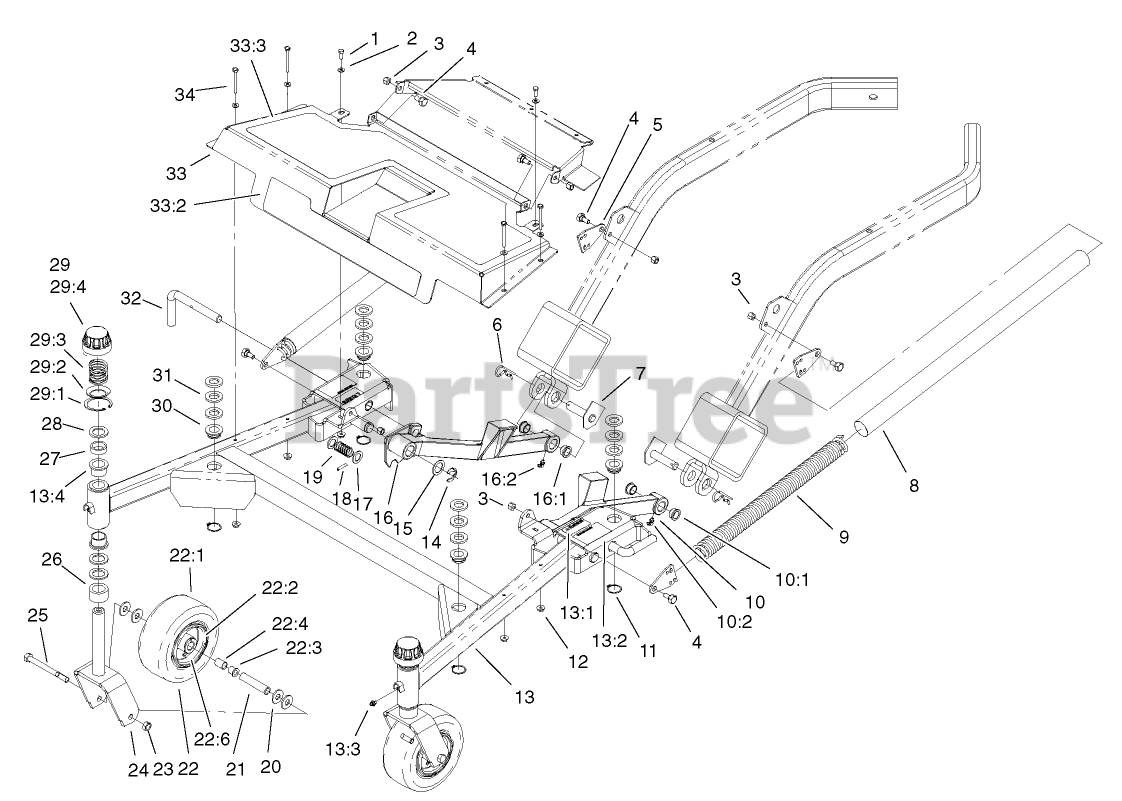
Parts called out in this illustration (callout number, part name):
1	SCREW-HH
2	WASHER-FLAT
3	NUT-LOCK, NI
4	BOLT-SHOULDER
5	PLATE-END, SPRING
6	PIN-HAIR
7	PIVOT PIN ASM
8	COVER-SPRING
9	SPRING-EXTENSION
10	LH PUSHARM ASM
10:1	BEARING-FLANGE
10:2	FITTING-GREASE
11	RING-RETAINING
12	NUT-HF
13	CARRIER FRAME ASM
13:1	DECAL-WARNING
13:2	DECAL - HOC, CE
13:3	FITTING-GREASE
13:4	BUSHING
14	RING-RETAINING
15	Washer
16	RH PUSHARM ASM
16:1	BEARING-FLANGE
16:2	FITTING-GREASE
17	WASHER
18	PIN-ROLL
19	SPRING-COMPRESSION
20	WASHER-FLAT
21	SPANNER-TIRE
22	CASTOR WHEEL ASM
22:2	RIM ASM
22:3	BEARING-OUTSIDE
22:4	BEARING-ROLLER
22:6	FITTING-LUBE, 45 DEG
23	NUT-HEX
24	CASTOR FORK ASM
25	SCREW-HH
26	SPACER-CASTOR
27	SPACER
28	WASHER-THRUST
29	HOC CAP ASM
29:1	RING-RETAINING
29:2	WASHER-CAP
29:3	SPRING-COMPRESSION
29:4	CAP-HOC
30	BUSHING-DECK
31	WASHER-FLAT
32	PIN-PIVOT
33	FOOTREST ASM
33:3	PAD-FOOTREST
34	SCREW-HH
